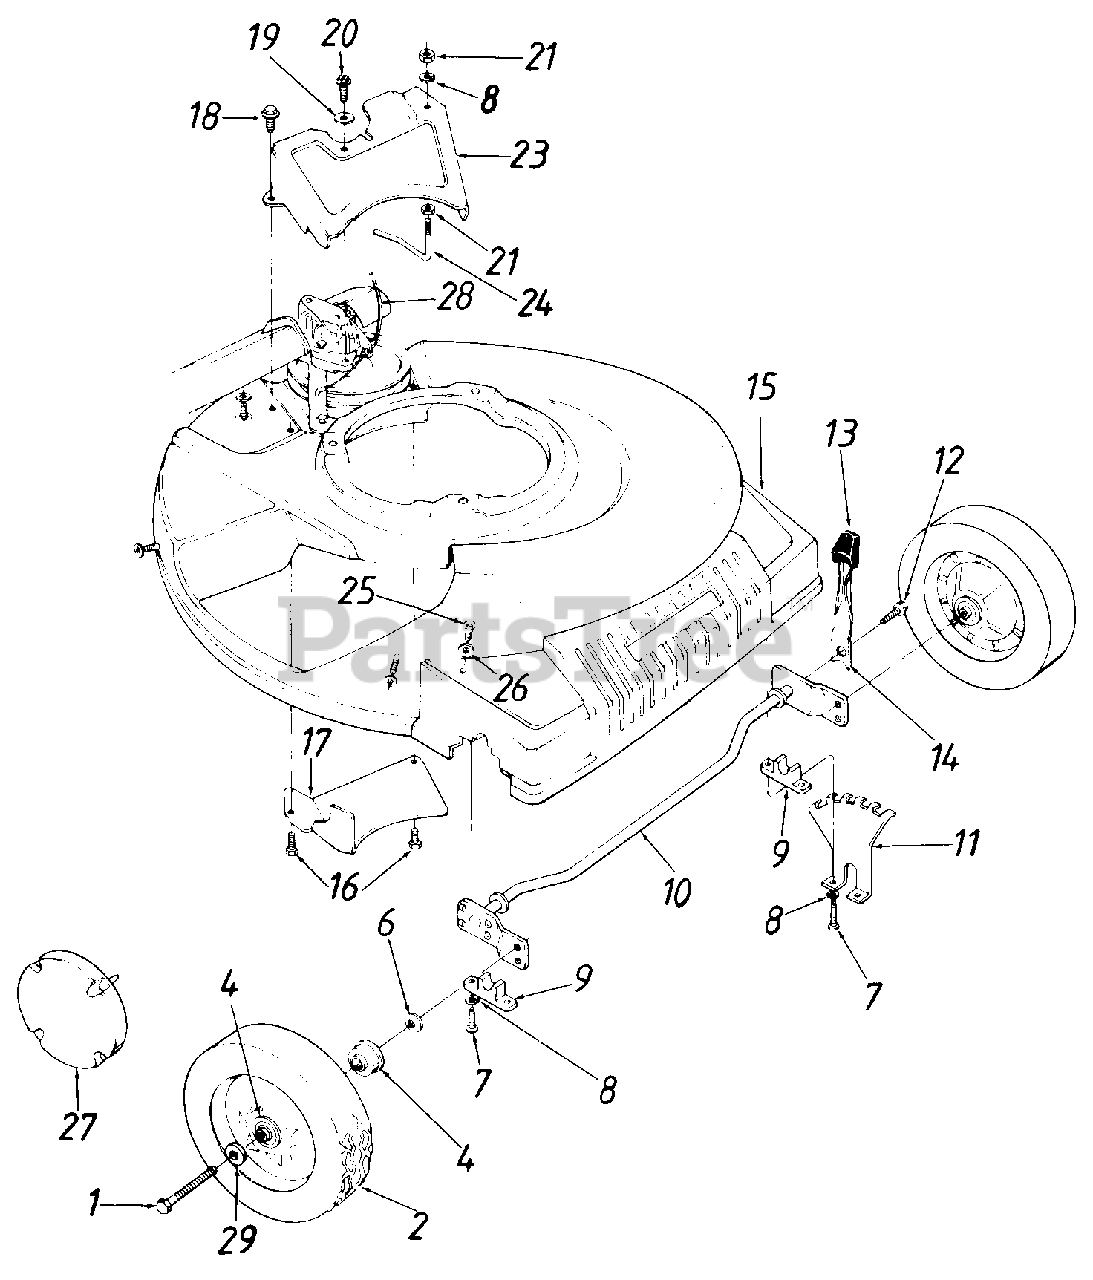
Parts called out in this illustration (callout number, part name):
1	Front Axle Bolt
2	Wheel Ass'y. Comp. 8 x 2"
4	Flange Ball Brg. .501" I.D.
6	Bell-Wash. .400" I.D. x .88
7	Hex B-Tap Scr. 1/4-20
8	L-Wash. 1/4" I.D.
9	Block Bushing
10	Axle Ass'y.
11	Height Adj. Bracket
12	Hex Wash. Hd. B-Tap Scr. 1/4-20 x .75" Lg.
13	Knob
14	Spring Lever
15	Plastic Front End
16	Hex B-Tap Scr. 1/4-.38"
17	Belt Cover
18	Hex Wash. Hd. TT-Scr. 1/4-20
19	Bell-Wash. .265" I.D. x .75"
20	Hex Wash. Hd. B-Tap Scr. 1/4 x.62"
21	Hex Nut 1/4-20 Thd.
23	Transmission Belt Guard
24	S.P. Belt Guard
25	Truss B-Tap Scr. 5/16 x .75" Lg.
26	Bell-Wash. 5/16" I.D. x 5/8
27	Hub Cap
28	S.P. Cable 50" Lg.
29	Fl-Wash. .531" I.D.
